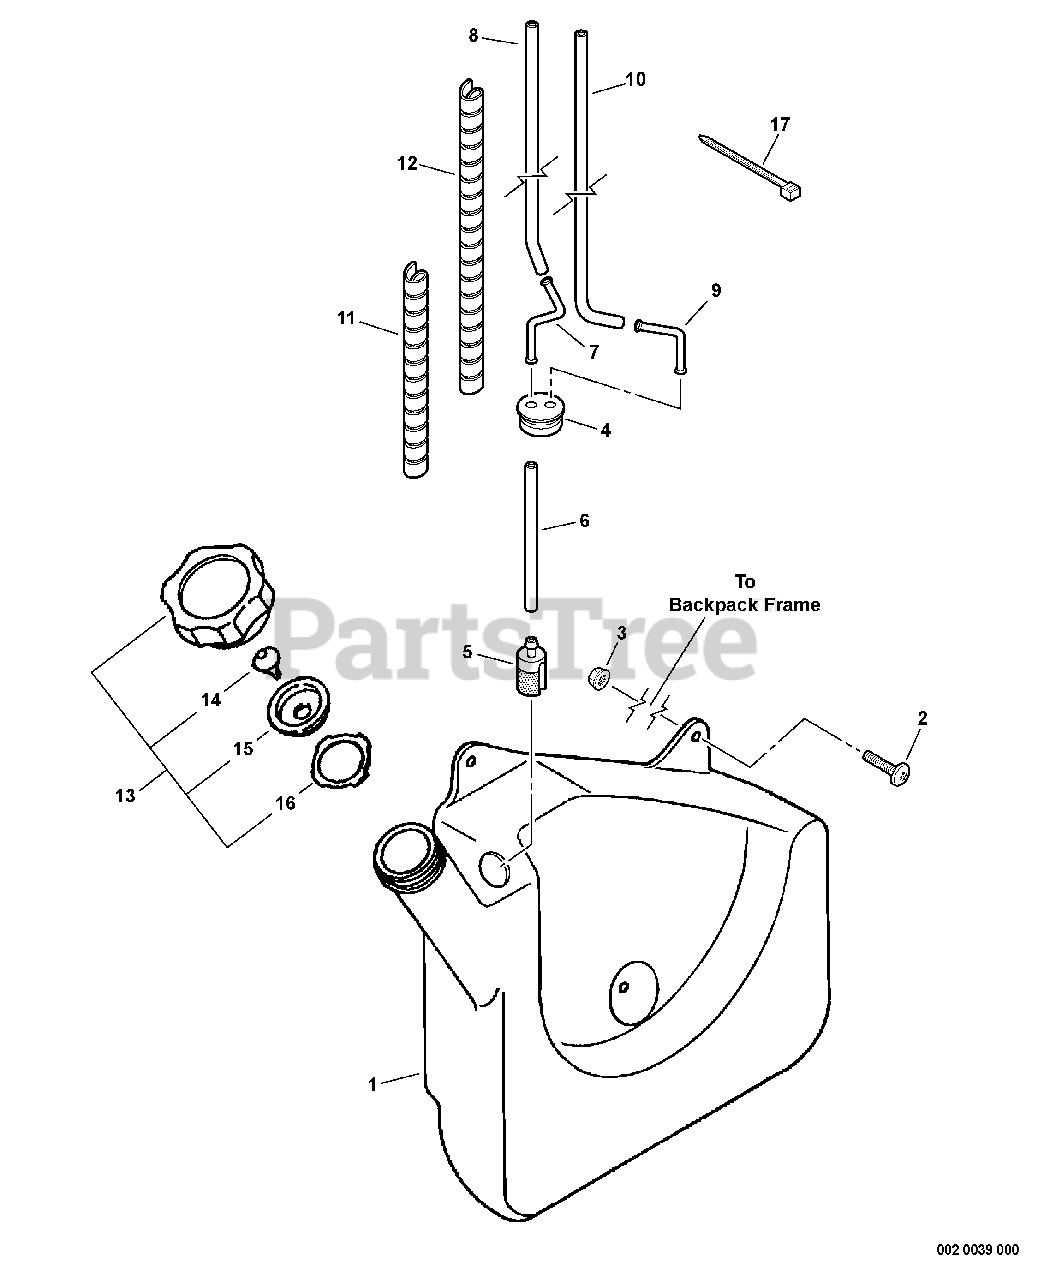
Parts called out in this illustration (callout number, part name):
1	TANK, FUEL
2	SCREW 5×20
3	NUT, LOCK M5
4	GROMMET
5	FILTER, FUEL
6	PIPE, FUEL 3×6×280 MM
7	CONNECTOR, PIPE
8	PIPE, FUEL
9	CONNECTOR, PIPE
10	PIPE, FUEL
12	WRAP, SPIRAL
13	CAP ASSY
14	VENT ASSY
15	HOLDER, CHECK VALVE
16	GASKET, FUEL CAP
17	TIE, CABLE
